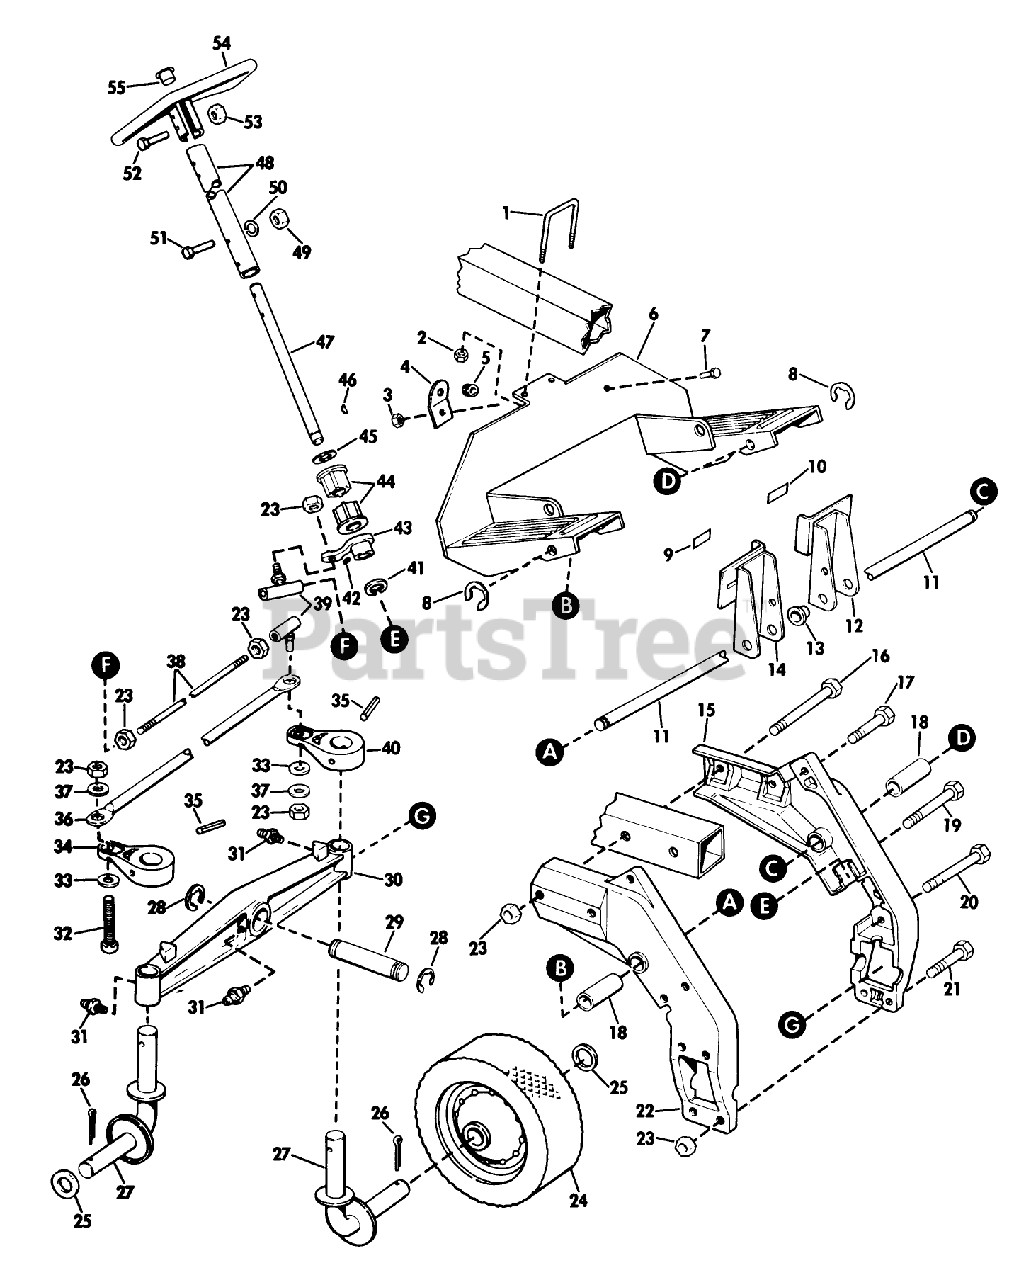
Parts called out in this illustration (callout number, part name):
5	Bushing
31	Grease Fitting
32	Screw-King Pin
53	Nut-Steering Shaft
